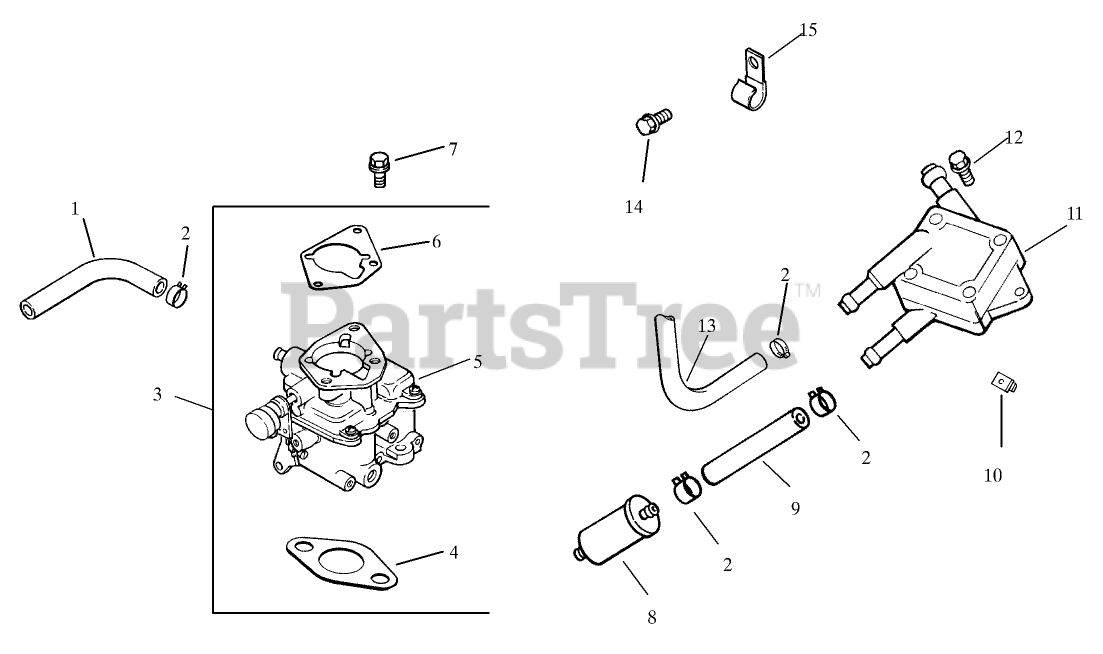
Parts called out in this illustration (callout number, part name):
1	Line-Fuel (9.5)
2	CLAMP-HOSE, SPRING (1/2)
3	Kit, carburetor w/gasket (Includes 4-6)
4	Gasket-Carburetor
5	Carburetor asm (For information only not available separately)(Service with: 24 757 01-S, 24 757 02-S, 24 757 03-S, 24 757 07-S, 24 757 08-S, 24 757 09-S)
6	GASKET-BASE, AIR CLEANER
7	SCREW-FLANGE (M6X1.0X30)
8	Filter-Fuel
9	Line-Fuel (3.5)
10	Nut-Plastic
11	PUMP-FUEL
12	SCREW-TAP (M6X1.7X18)
13	Line-Fuel, Flexible (15.5)
14	Screw-HF (M6x1.0x12)
15	CLIP-CABLE
